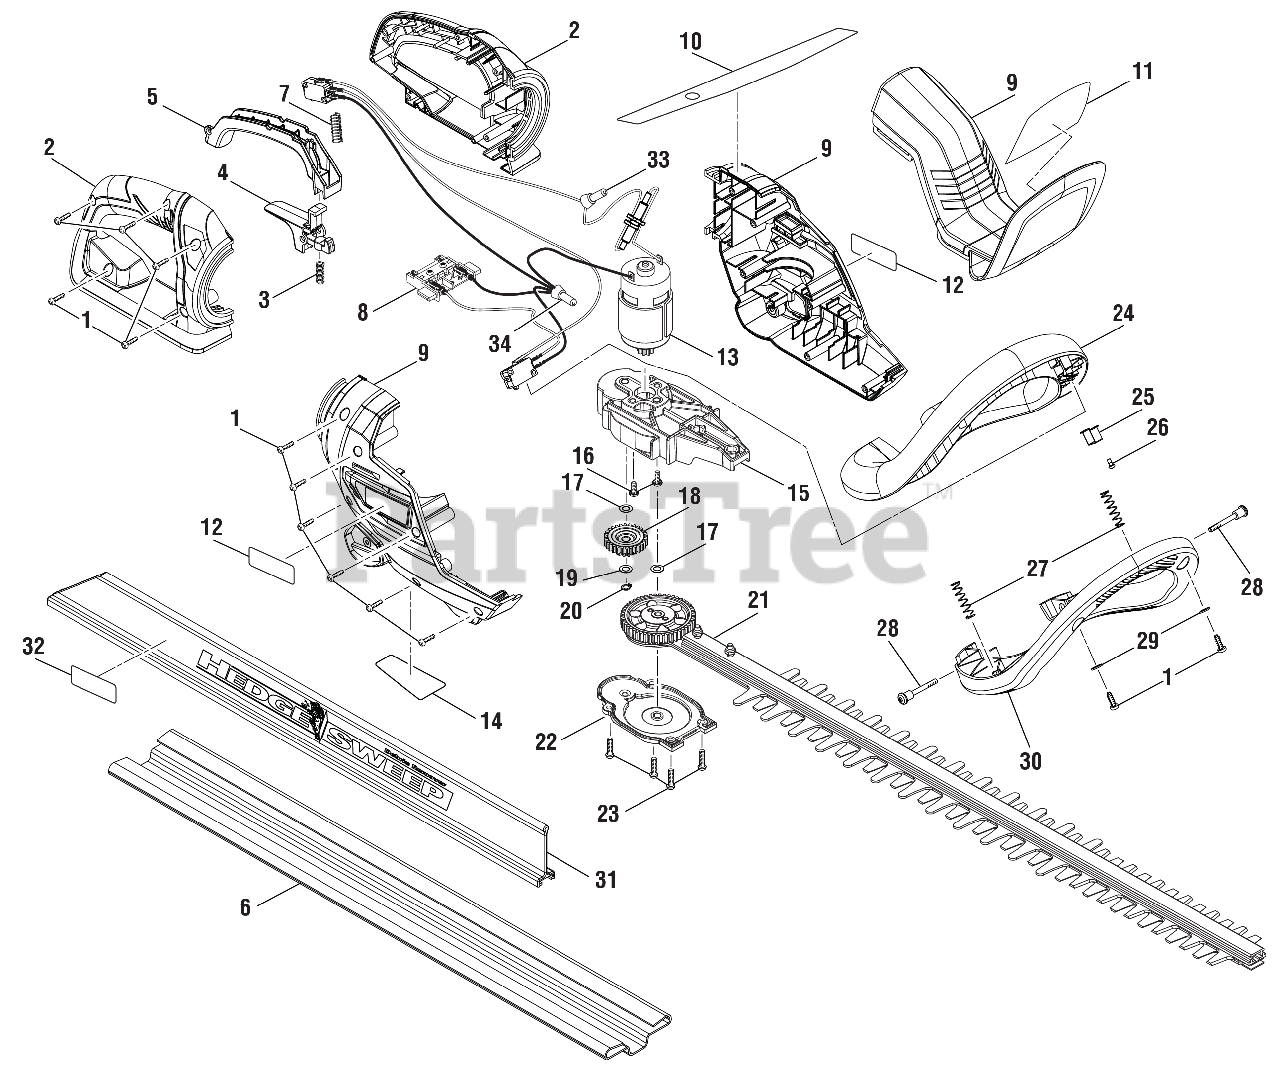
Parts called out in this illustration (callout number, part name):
1	Screw (M4 x 13.5 mm, T15 Torx Pan Hd.)
2	Rear Handle Assembly
3	Compression Spring
4	Lock-off Trigger Assembly
6	Scabbard, PP
7	Compression Spring
8	Switch and Contact Plate Assembly
9	Motor Housing Assembly (Inc. Key Nos. 10-12 & 14)
10	Angle Adjustment Label
11	Warning Label
12	Logo Label
13	Motor Assembly
14	Data Label
15	Gear Case
16	Screw w/Tooth Washer (M4 x 12 mm, Pan Hd.)
17	Washer (M6, ID6.2 x 11OD x 0.3t)
18	Middle Gear Assembly
19	Flat Washer (OD10 x ID5.3 x 0.5t)
20	Retaing Ring
21	Blade Assembly (24 in.)
22	Gear Case Cover
23	Screw (M4 x 16 mm, Pan Hd.)
24	Front Handle
25	Switch Board, SPCC, Black Zinc Plated
26	SCREW, CH M3 PH B\L=6MM
27	Spring,Handle Cover, Dia. 7, SWC
28	Screw (M4 x 38 mm, T20 Torx Pan Hd.)
29	Flat Washer (OD10 x ID42 x 1t)
30	Front Handle Cover
31	Hedge Sweep (Inc. Key No. 32)
32	Warning Label
33	Wire Connector (Closed End)
34	Wire Connector (Closed End)
